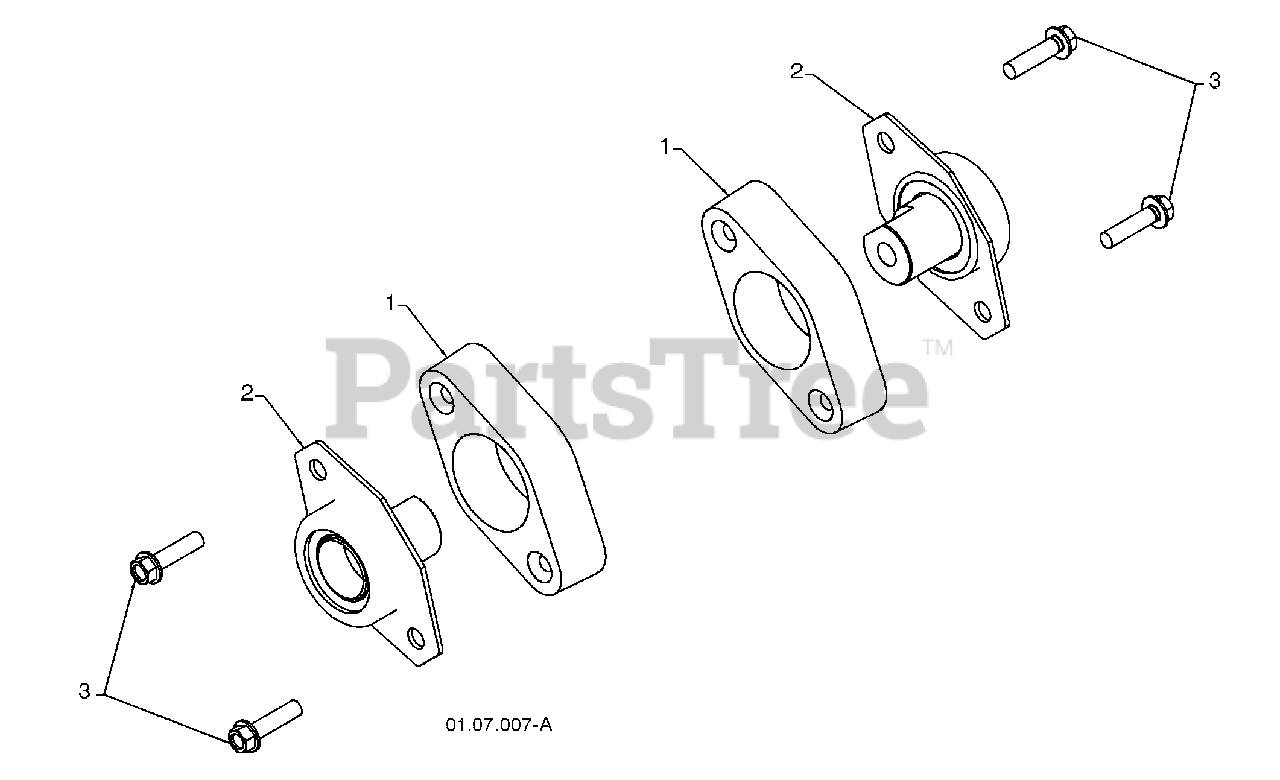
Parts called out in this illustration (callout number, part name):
1	PLASTIC RETAINER
2	AUGER BALL BEARING
3	SCREW 5/16-18 X 1.00
